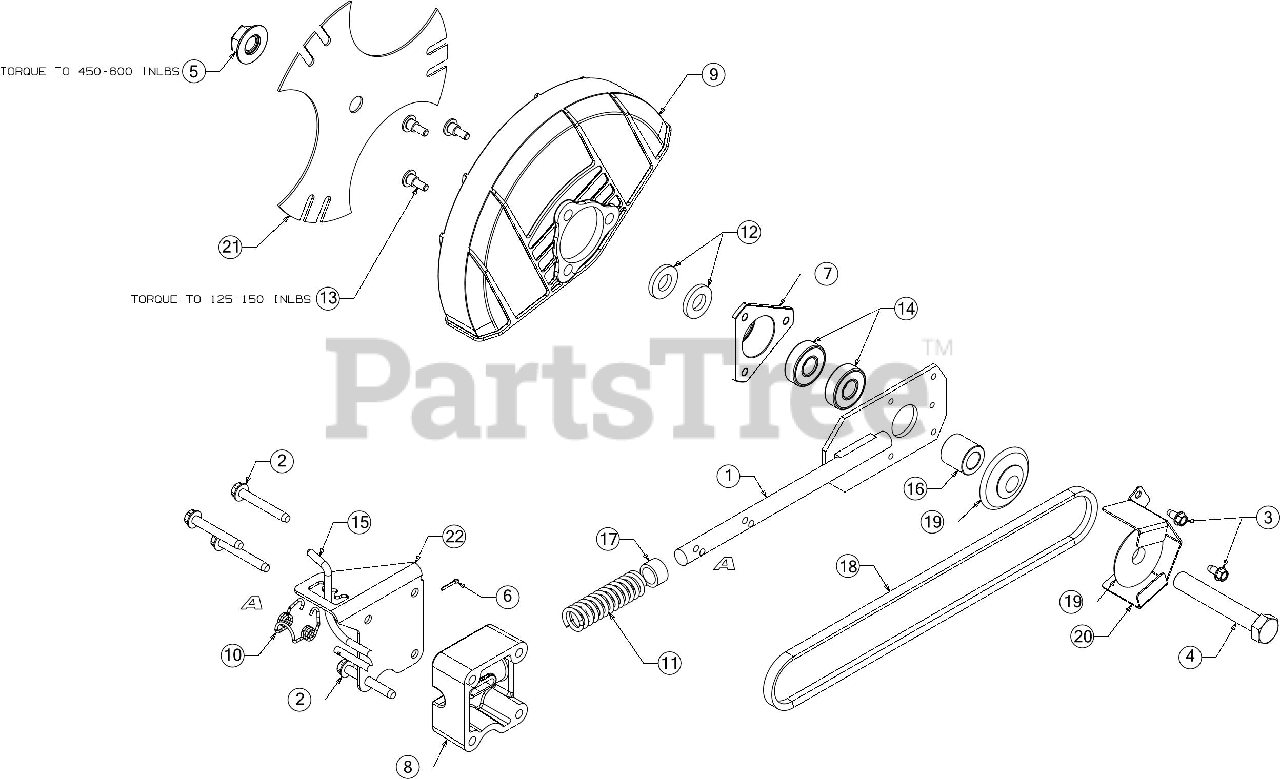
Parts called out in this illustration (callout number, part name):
1	BLADE PLATE ASSEMBLY
3	SCREW 1/4-20 X.500
4	SCREW 5/8-18 X 4 GR5
5	HEX NUT
6	COTTER PIN-3/32X62
7	BEARING CUP
8	BEARING BLOCK
9	BLADE GUARD
10	TORSION SPRING
11	COMPRESSION SPRING
12	FLAT WASHER .635 X 1.24 X .181
13	SHOULDER SCREW .375X.280:1/4-14
14	BALL BEARING
15	ADJUSTMENT ROD
16	SPACER
17	SPACER
18	BELT 3L X 35.8
19	SHEAVE
20	BELT GUARD-
21	BLADE TRI-CUT (POWDER BLACK)
22	INDEX BRACKET
